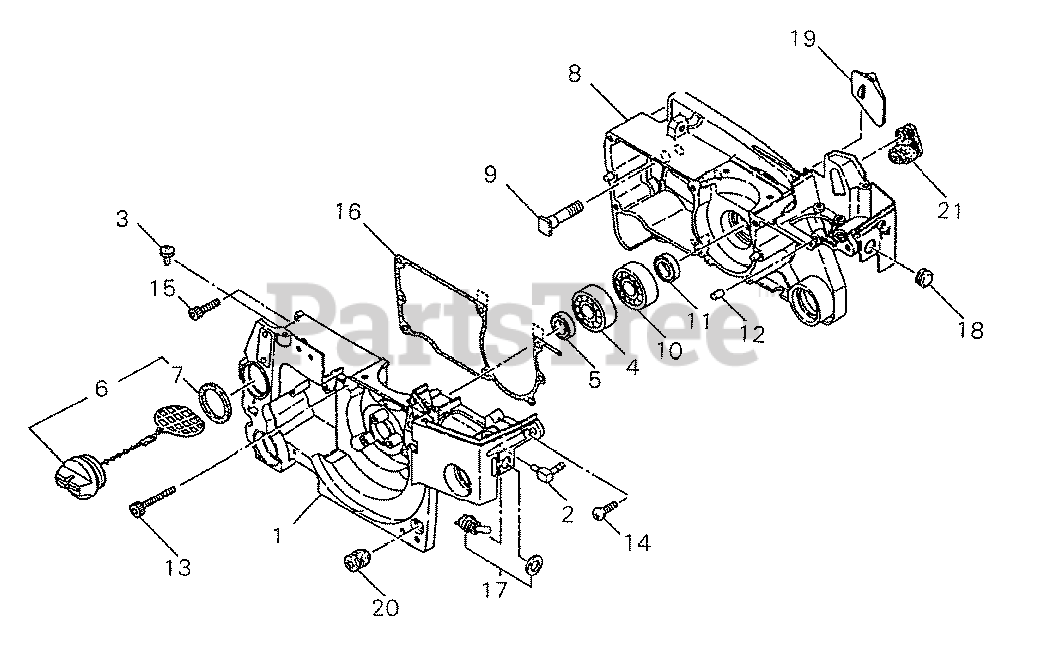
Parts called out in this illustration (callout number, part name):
1	CRANKCASE - LEFT
2	CONNECTOR, PIPE
3	VALVE, OIL
4	BEARING, BALL - 6201C3
5	SEAL, OIL
6	CAP ASSY
7	GASKET
8	CRANKCASE - RIGHT
9	STUD, GUIDE BAR
10	BEARING, BALL - 6201C3
11	SEAL, OIL
12	PIN - LOCATING
13	SCREW - 5X30
14	SCREW - 5X12
15	SCREW - 5X18
16	GASKET, CRANKCASE
17	SWITCH ASSY
18	PLUG
19	STOPPER
20	SUPPORT
21	GROMMET (NON EPA)
